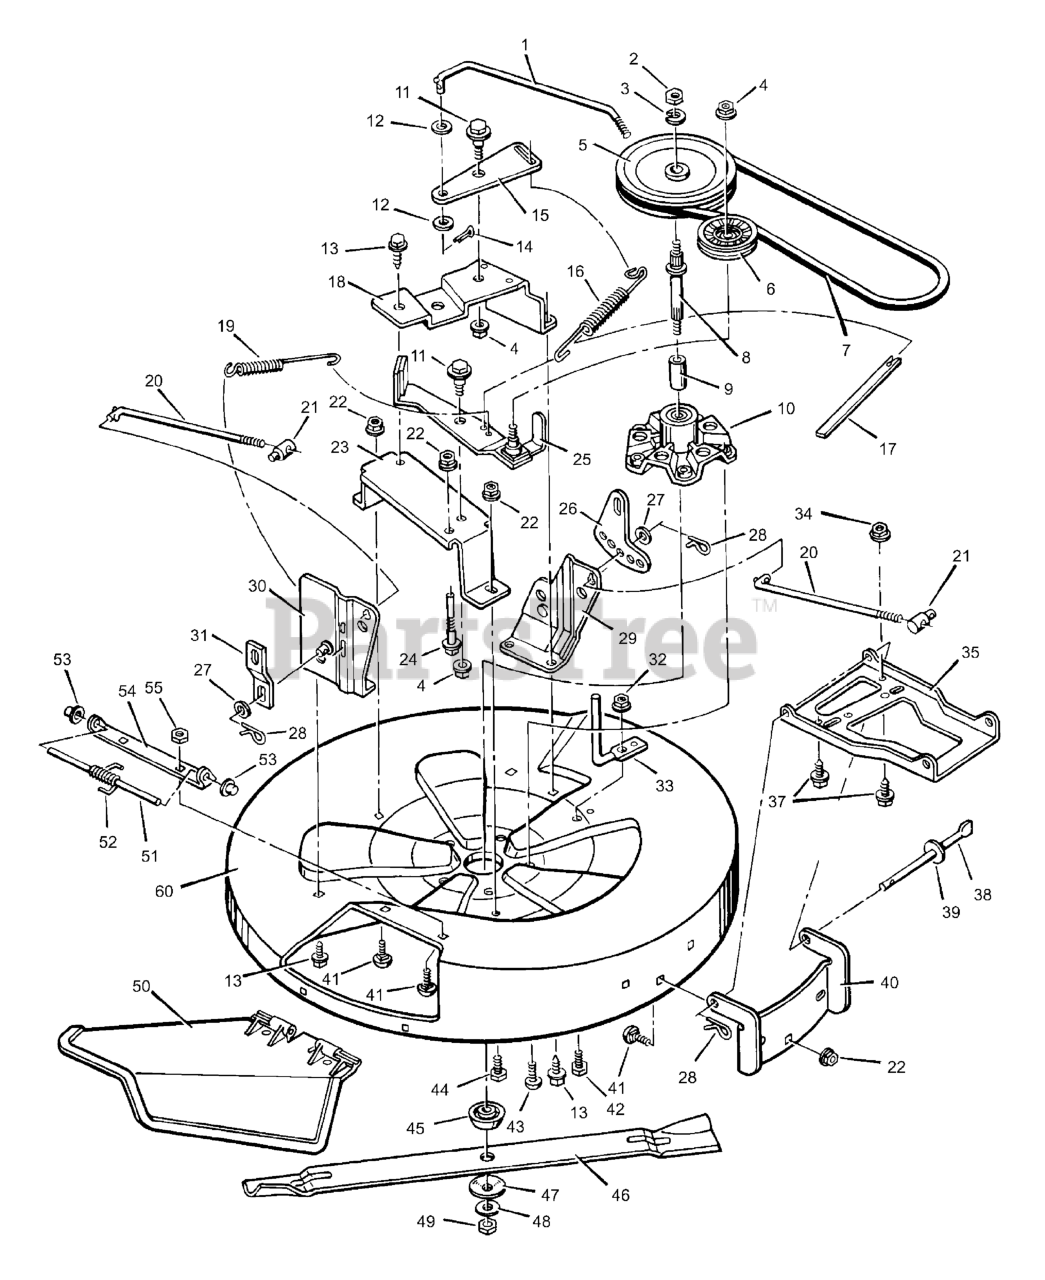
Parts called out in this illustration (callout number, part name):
1	Rod, PTO
2	Locknut
3	Lockwasher
4	Locknut, Flange
5	Pulley, Splined
6	Pulley, Idler
7	Belt, Mower Drive
8	Mandrel
10	Housing, Mandrel
11	Bolt, Shoulder
14	Pin, Cotter
15	Bracket, Pivot
16	Spring, Extension
17	Indicator, Plastic
18	Support, Pivot Bracket
19	Spring, Extension
20	Rod, Adjusting
21	Nut, Adjustable
22	Nut, Flange
23	Support, Idler Arm
24	Guide, Belt
25	Arm Assembly, Idler
26	Plate, Adjusting
28	Pin, Hair
29	Bracket Assembly, Left Lifter
30	Bracket Assembly, Right Lifter
32	Nut, Flange
33	Guide, Belt
34	Nut, Hex
35	Hanger, Front
38	Rod, Hanger
40	Bracket, Front Hanger
41	Bolt, Carriage
42	Bolt
44	Bolt
45	Adapter, Blade
47	Washer, Belleville
49	Nut, Hex
50	Deflector, Chute
51	Rod, Deflector
52	Spring - Torsional
53	Cap, Push On
54	Hinge, Deflector
55	Locknut
57	Bolt, Carriage
58	Wingnut
60	Mower Housing, Complete
